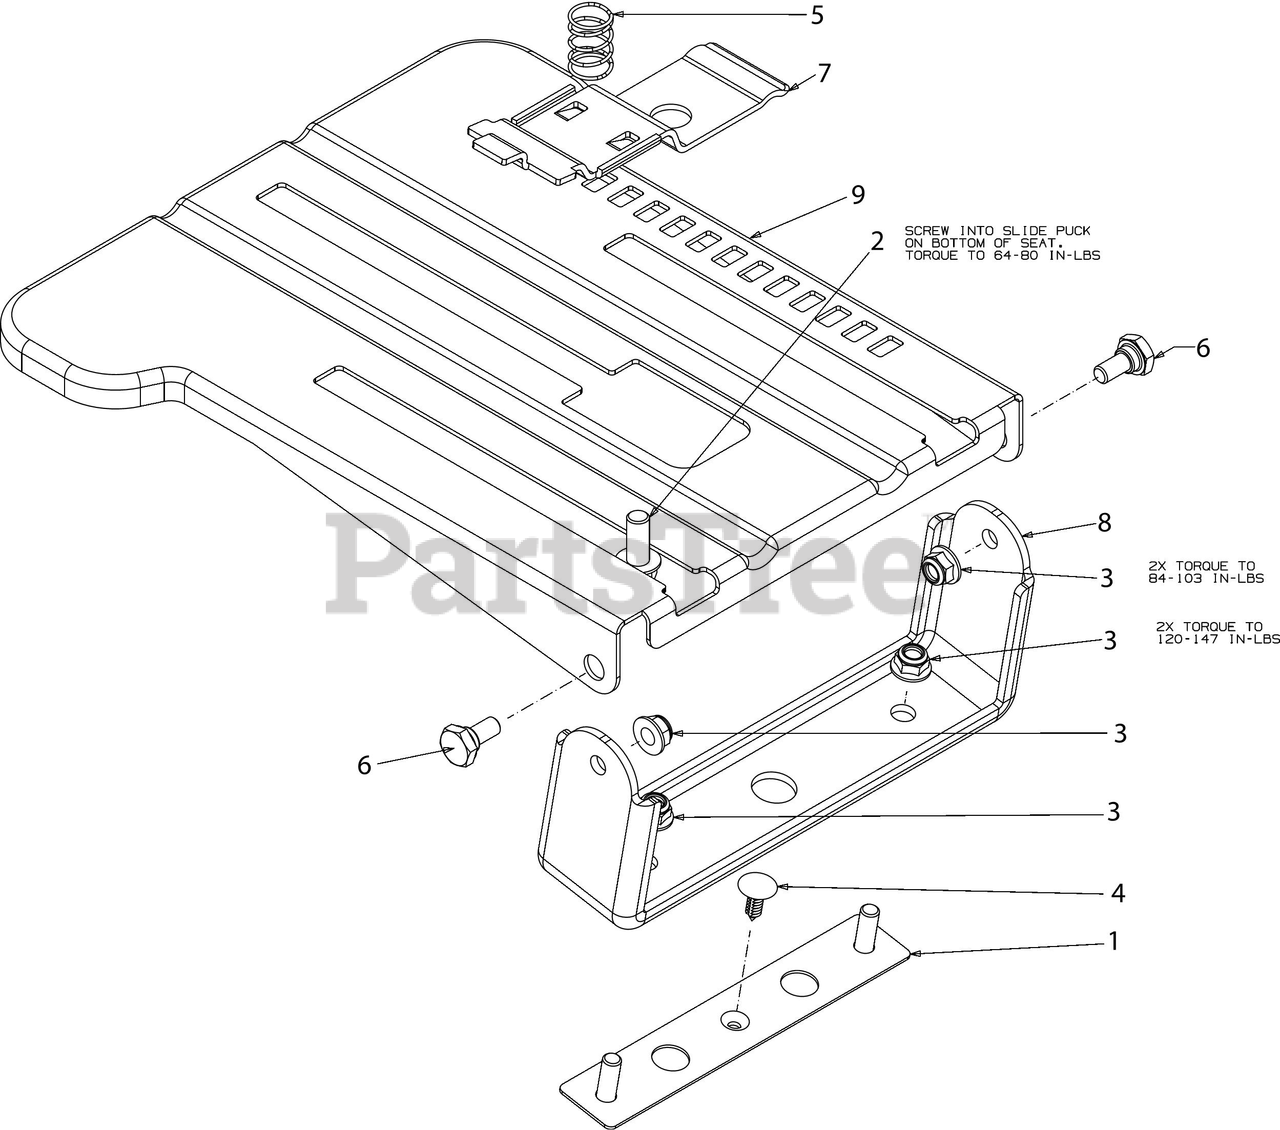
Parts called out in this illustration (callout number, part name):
1	PIVOT BRACKET PLATE
2	SCREW 3/8-16 x .875 GR5
3	FLANGE LOCK NUT 5/16-18
4	RATCHET CLIP .250
5	COMPRESSION SPRING
6	SHOULDER SCREW .44 DIA X .18
7	SEAT ADJUST LEVER
